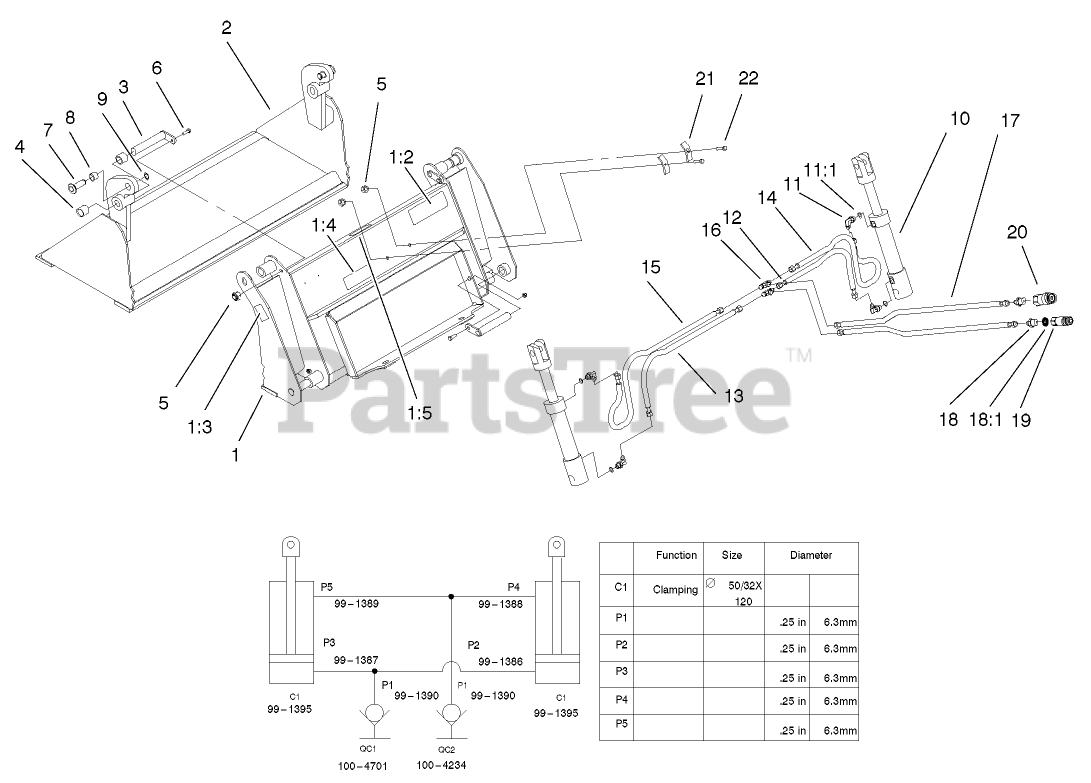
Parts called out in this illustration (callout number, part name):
1	Base ASM
1:2	DECAL-WARNING
1:3	DECAL-WARNING
1:4	DECAL-LOAD RATING
1:5	DECAL-ATTACHMENT, DINGO
4	BUSHING
5	NUT-LOCK, NI
6	SCREW-HHF
8	BUSHING
9	Ring-Snap
10	CYLINDER - HYDRAULIC
11	FITTING-ELBOW, 90 DEG
11:1	O-RING
12	HOSE ASM-HYDRAULIC
13	HOSE ASM-HYDRAULIC
14	HOSE ASM-HYDRAULIC
15	HOSE ASM-HYDRAULIC
16	ADAPTER - TEE
17	HOSE ASM-HYDRAULIC
18	ADAPTER-HYD
18:1	O-RING
19	NIPPLE-CONNECT, PRESSURE
20	COUPLER-FACE, FLUSH
21	CLAMP - HOSE
22	SCREW-HHF
